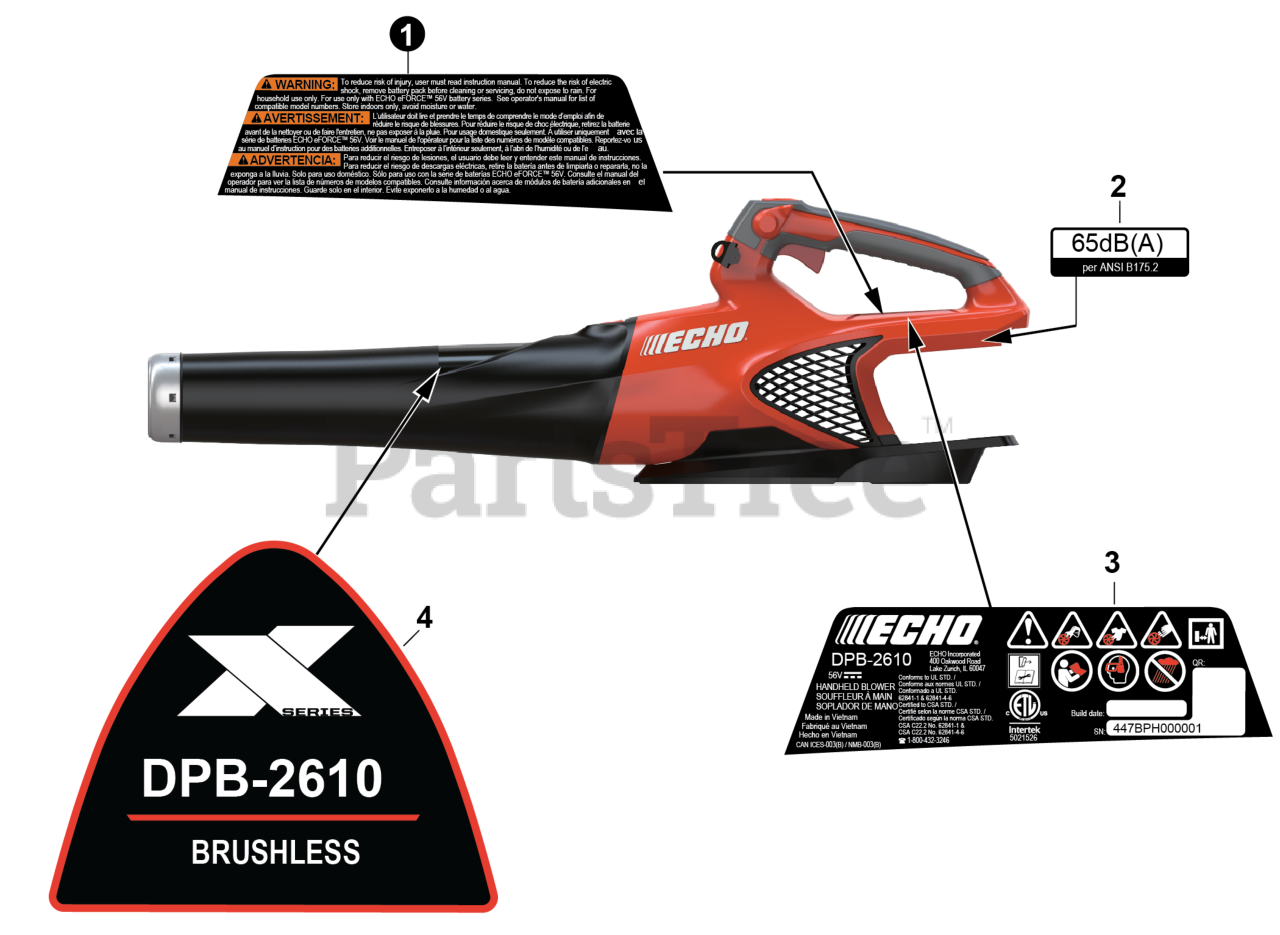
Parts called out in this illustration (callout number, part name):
1	LABEL, WARNING
2	LABEL, DECIBEL
3	LABEL, WARNING/SERIAL
4	LABEL, MODEL
